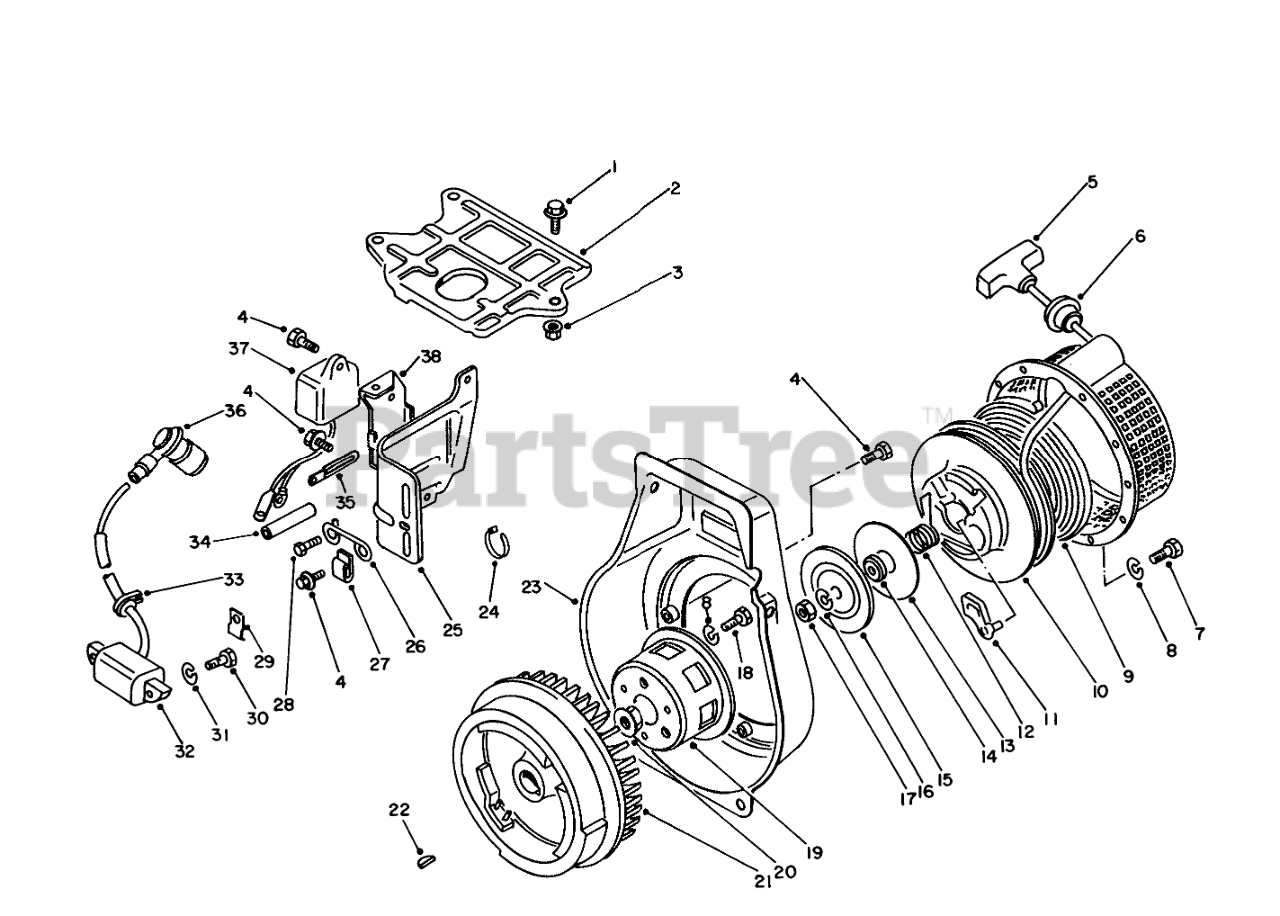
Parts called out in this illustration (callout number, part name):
2	Cowling-Upper
3	M6 X 1 LOCKNUT
5	Grip
6	Grip Assembly (Incl. Ref. #35)
8	Lockwasher
9	SPRING
11	Ratchet
12	Spring
13	Plate-Slide
14	Cover
15	Plate
16	WASHER-LOCK
19	Pulley-Starter
21	Rotor
23	Cover-Cooling Fan
24	Clamp
25	Cowling Side
26	CLAMP
27	Clamp
28	SCREW-HHF
29	Clamp
31	Washer-Lock
32	Stater
33	Grommet
34	CAP CONNECTOR
35	Clamp
36	SPARK PLUG CAP
37	Unit-Transistor Magneto
38	Bracket
